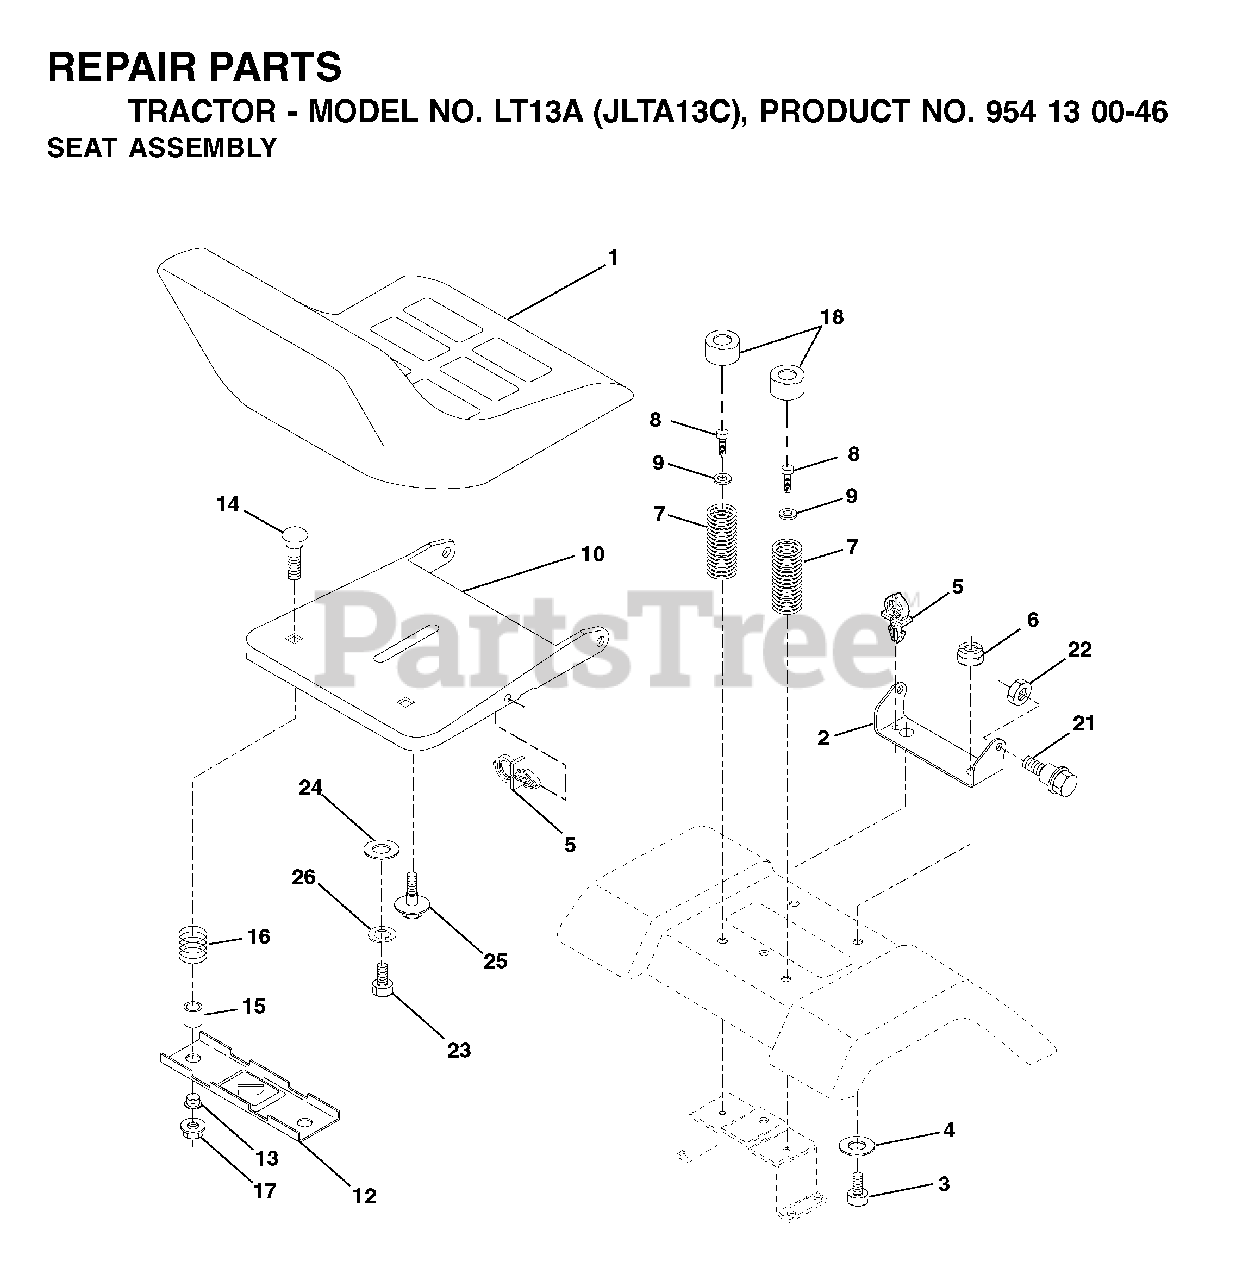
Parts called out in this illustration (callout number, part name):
2	SEAT PIVOT BRKT
4	WASHER PM
5	PUSH CLIP
6	NUT
7	SPRING COMPRESSION
8	SCREW 3/8-16X1
9	WASHER
10	PAN, SEAT
12	BRKT SWITCH
14	BOLT.ROUND.HEAD.SQUARE.NECK
15	SPACER SPLIT 28X.96
17	NUT T
18	CAP SPRING
21	BOLT.SHOULDER.5/16-18
22	NUT.71038.31-18.HEX.NYLOCK
23	BOLT.HEX.BLACK
25	BOLT,SHOULD
26	LOCKWASHER
